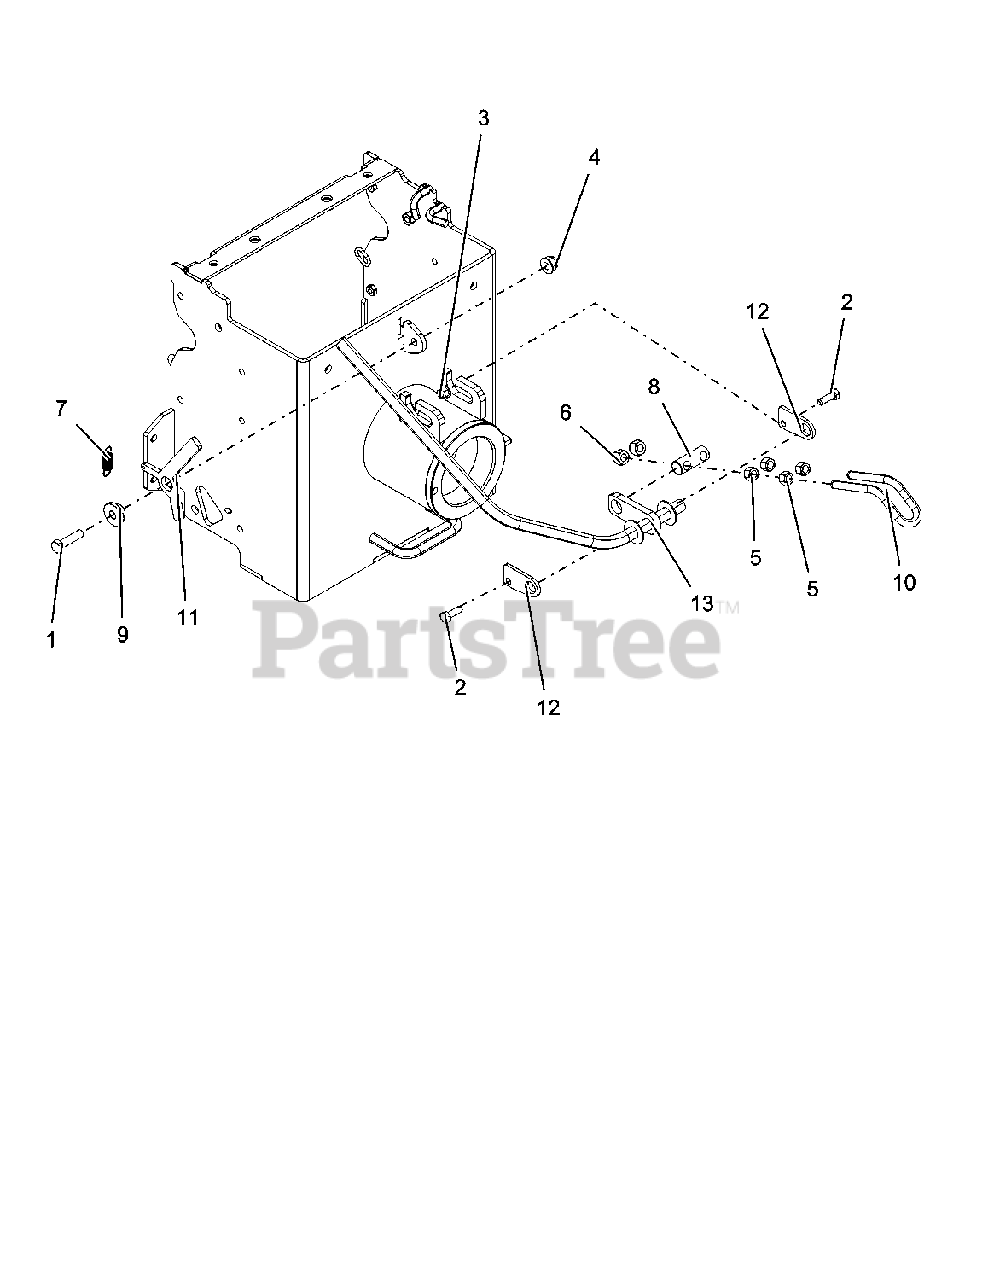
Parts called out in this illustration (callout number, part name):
1	BLT, HEX M10-1.5X40 GR8.8 ZC120
2	BLT, HEX M8-1.25X25 GR8.8 ZC120
3	NUT, LK-NYL-FLG M8-1.25 GR8.8 ZC120
4	NUT, LK-NYL-FLG M10-1.5 GR8.8 ZC120
5	NUT, HEX M10-1.5 A2CL70 SS
6	NUT, LK-NYL M10-1.5 A2CL70 SS
7	SG-TENS .041X.500X1.750
8	ROD, PIVOT
9	BSHG, STEP .413X.776X1.25X.413
10	LATCH, BOW
11	LOCK, HANDLE (BLACK)
12	PLATE, LOCK LEVER-BLACK
13	WLDMT, LEVER ATTACHMENT-BLACK
